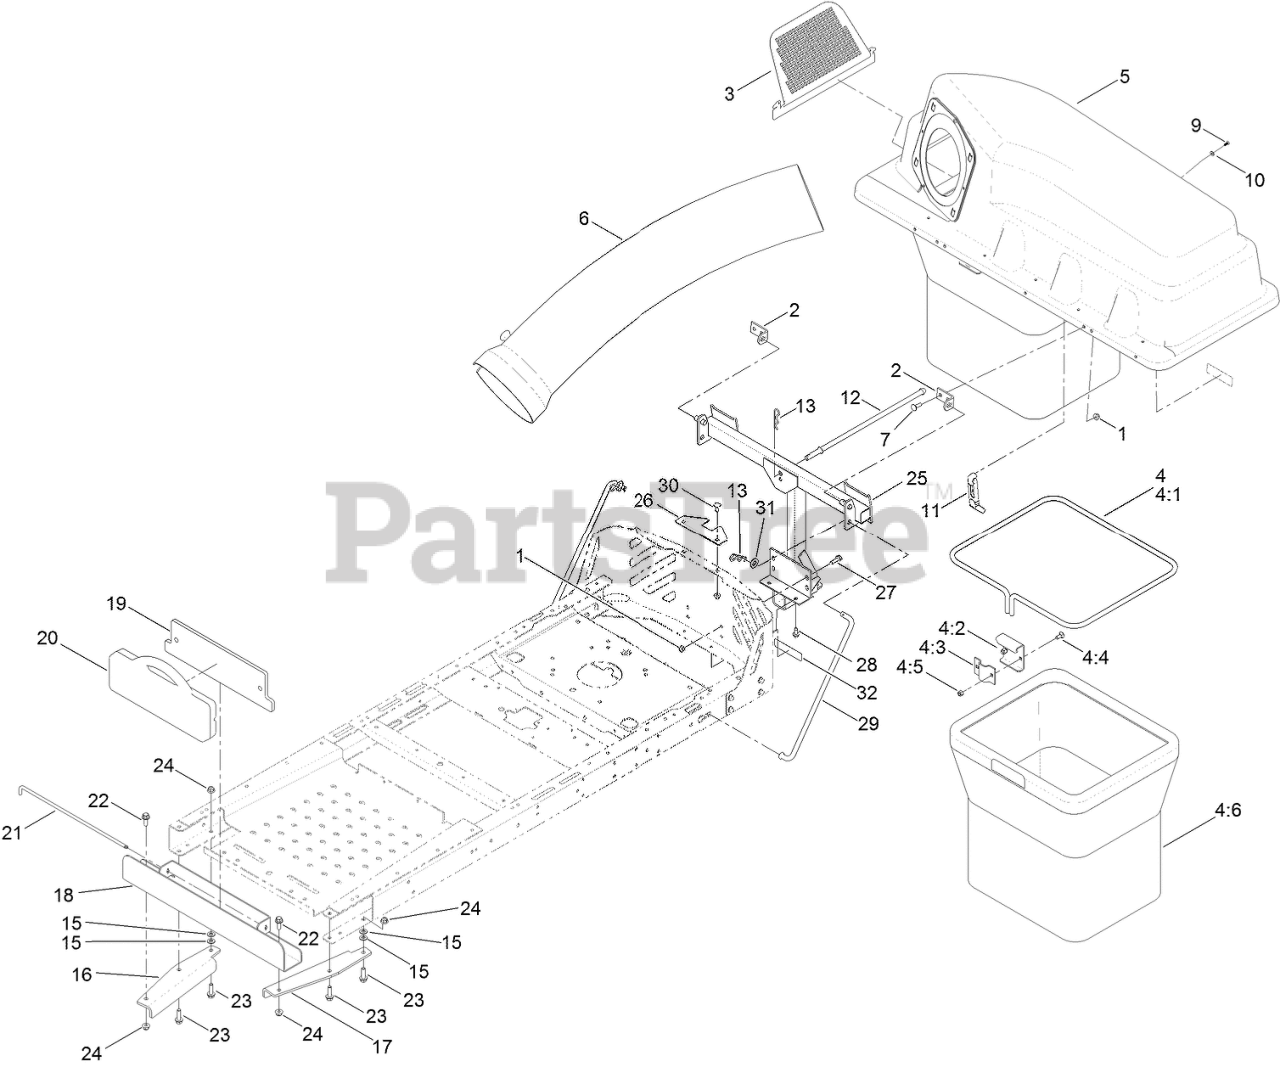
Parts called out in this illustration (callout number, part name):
1	NUT-HF, NI
2	BRACKET-PIVOT, HOPPER
3	SCREEN-BAGGER
4	BAG ASM
4:1	FRAME-BAG
4:2	HANGER-BAG
4:4	BOLT-CARR
4:5	NUT-LOCK, NI
5	BAGGER TOP ASM
6	TUBE-BAGGER
7	BOLT-CARR
9	SCREW-PLASTITE
10	WASHER-FLAT
11	LATCH-RUBBER
12	ROD-HOOD, DOWN (HOLD)
13	PIN-HAIR
15	WASHER-FLAT
16	BRACKET-BAGGER WEIGHT, RH
17	BRACKET-BAGGER WEIGHT, LH
18	CHANNEL-WEIGHT, BAGGER
20	WEIGHT-35 POUND
21	PIN-WEIGHT
22	SCREW-HHF
23	SCREW-HHF
24	NUT-HF, NI
25	FRAME-PIVOT
26	BRACKET-STABILIZER
27	SCREW-HHF
28	SCREW-HWHTF
29	ROD-SUPPORT
30	BOLT-CARR
31	WASHER-FLAT
